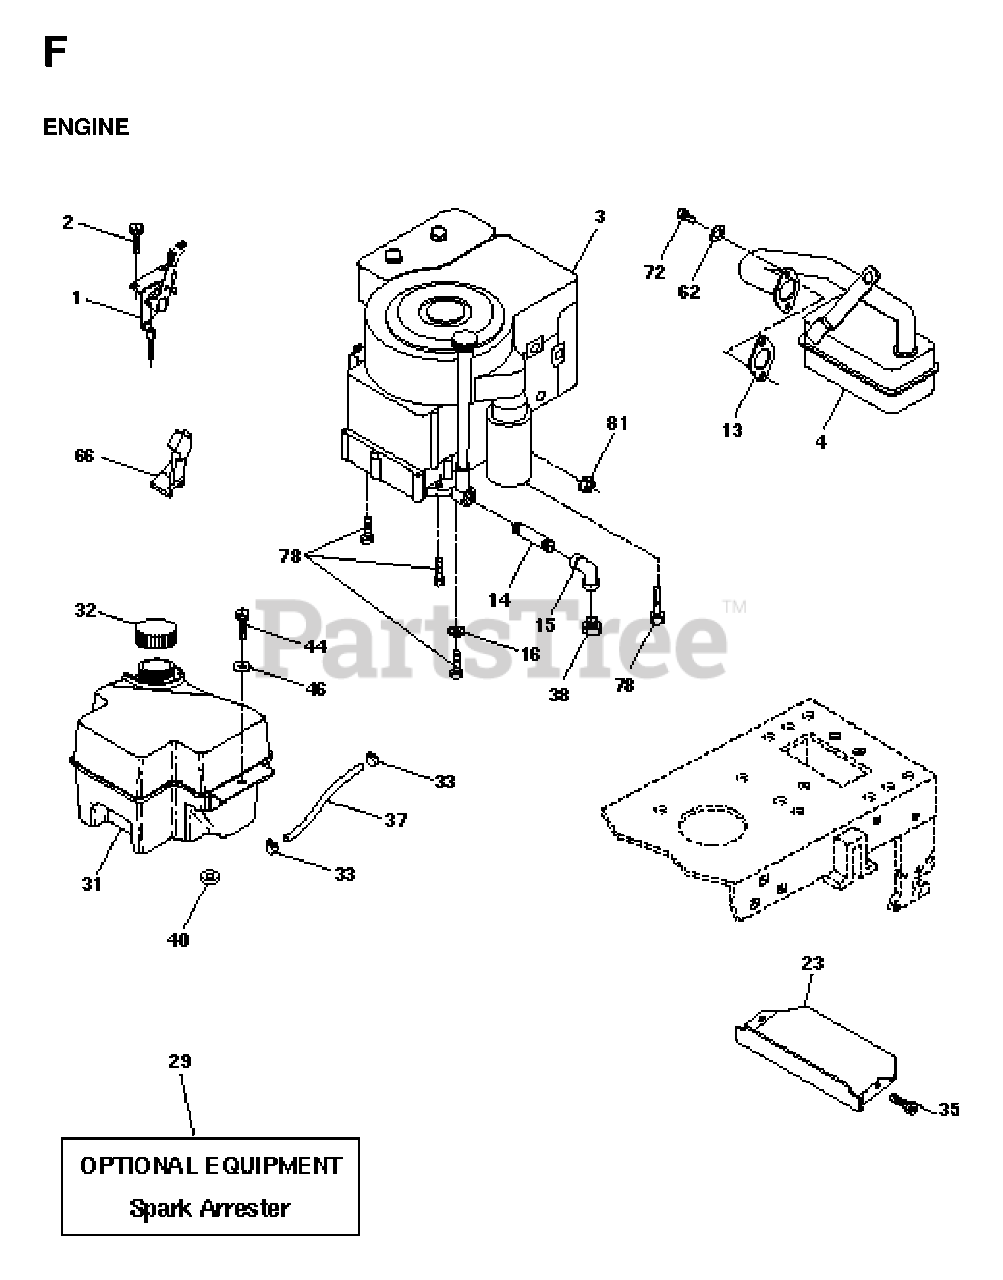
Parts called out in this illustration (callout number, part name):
1	CONTROL
2	SCREW LT
13	GASKET ENG
15	ELBOW
16	LOCKWASHER
23	PROTECTOR
29	ARRESTER SPARK (OPTIONAL)
31	FUEL TANK
32	FUEL CAP
33	HOSE CLAMP
35	SCREW
37	LINE.FUEL.20
40	GROMMET T
44	SCREW HEX CRT
62	LOCKWASHER
66	STOP THROTTLE
72	SCREW
78	SCREW
81	NUT FLANGE 1/4-20 STARTER NUT
